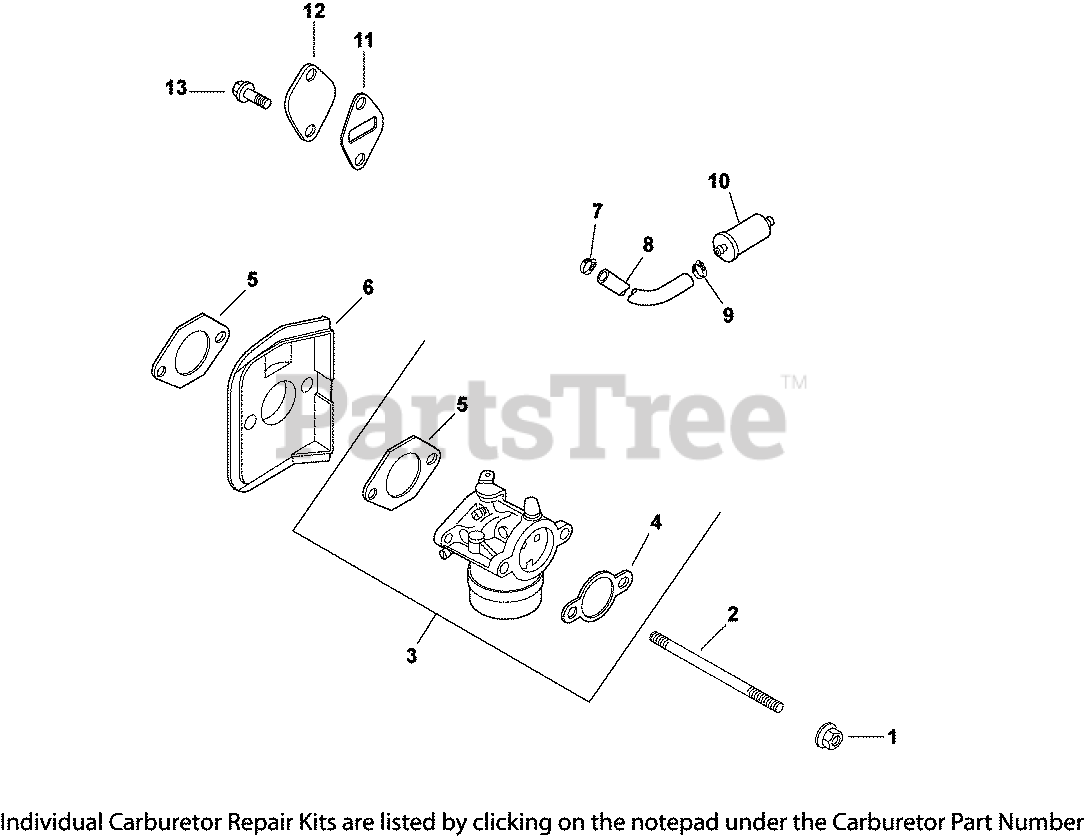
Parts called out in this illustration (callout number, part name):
1	NUT, FLG M6X1.0
2	STUD,M6X1.0X116
3	KIT, CARB W/GASKETS - USE 12 853 177-S
4	GASKET, AIR CLEANER BASE
5	GASKET, CARBURETOR
6	DEFLECTOR, HEAT
7	CLAMP, HOSE (KM)-USE 25 237 31-S
8	HOSE,LW PERM.FUEL 24.00"-USE 25 111 81-S
9	CLAMP, BAND SPRING HOSE-(#2523737S)
10	FILTR,FUEL 75 MICRON (GRAVTY FEED)
11	GASKET, FUEL PUMP
12	PLATE, FUEL PUMP COVER
13	SCREW,FLG THD FRM M6X1.0X16-(#25086397S)
